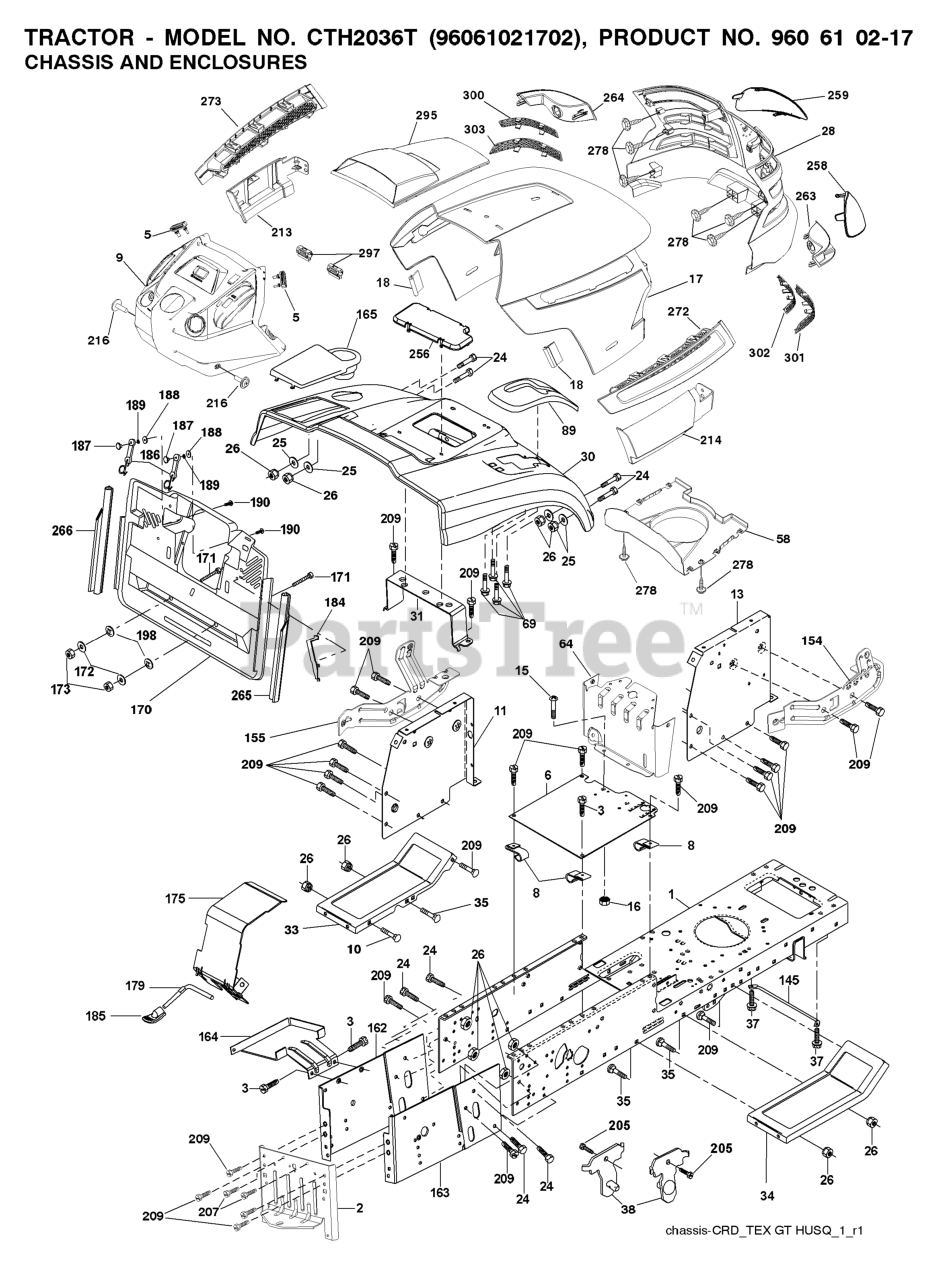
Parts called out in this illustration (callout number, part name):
2	DRAWBAR
3	SCREW 3/8-16X3/4
5	BUMPER DASH
6	PLATE
8	CLIP,INSULATOR
10	BOLT D
11	PANEL DASH LH
13	PANEL DASH RH
15	Screw, Machine, Truss Head 5/16-18 UNC x 3/4
16	NUT
17	HOOD
18	BUMPER.HOOD.TEX.HUSQVARNA
25	WASHER
26	NUT
28	GRILL.ASM.HUSQ.TG/CRD.W/TRIM
30	CONSOLE.CRD.AUTO.GRY
31	BRACKET SUPPORT FENDER
33	FOOTREST PNT LH
34	FOOTREST PNT RH
37	Screw 5/16-18 x 1/2 Hex, Self Tapping 5/16-18 x 1/2
38	BRACKET ASM PIVOT MOWER REAR
58	AIR.DUCT.HOOD.TEX.GT.HUSQ
69	SCREW.HI-LO.CONSOLE
89	CONSOLE.CRD.AUTO.GREY.2005
145	ROD.PIVOT.HOOD
162	BRACKET
163	BRACKET EXTEN CHASSIS RH CRD
165	RP.COVER.BATTERY.CRD.GREY
172	WASHER
175	DOOR TRAP
179	ROD PIVOT FBI
184	BRACKET.ACTUATOR.BAGGER.SRD
186	LATCH ASSY
187	WELDNUT
189	LOCKWASHER #10
190	SCREW
207	SCREW, 5/16-18 X 1/2
209	SCREW, 3/8-16X3/4
213	SKIRT.HOOD.SIDE.HUSQ.LH.GREY
214	SKIRT.HOOD.SIDE.HUSQ.RH.GREY
216	SCREW 14-20 X 5/8
256	COVER FENDER CRD
258	LENS.RH.TEX.GT.HUSQ.CL
259	LENS.LH.TEX.GT.HUSQ.CL
263	BEZEL.RH.TEX.GT.HUSQ
264	BEZEL.LH.TEX.GT.HUSQ
265	SEALING
266	SEALING
272	VENT.SIDE.HOOD.HUSQ.RH.GREY
273	VENT.SIDE.HOOD.HUSQ.LH.GRAY
278	SCREW.#10 X 0.750.BOS
295	HOOD VENT
297	CLIP.RETAINER.TINNER.
300	INSERT.HEX.GRILL.HUSQ.
301	INSERT.HEX.GRILL.HUSQ.GREY
302	INSERT.HEX.GRILL.HUSQ.
303	INSERT.HEX.GRILL.HUSQ.
